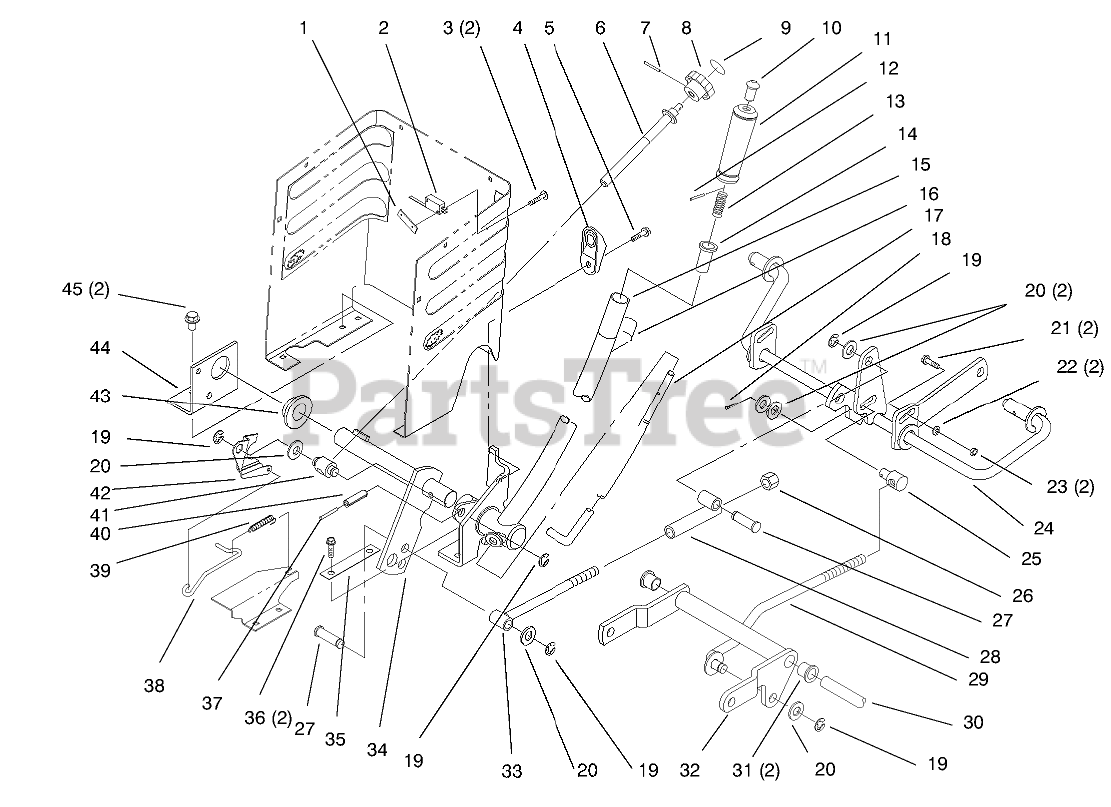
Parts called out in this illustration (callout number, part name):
1	NUT-SPEED
2	SWITCH-MICRO
3	SCREW-PPHTF
4	WEDGE - HOC
5	SCREW-HWH
6	ROD - HOC
7	PIN-SPIROL
9	DECAL-HEIGHT KNOB
10	TIP-ROD
11	GRIP-HANDLE
12	PIN-SPIROL
13	SPRING-COMPRESSION
14	RETAINER-SPRING
15	LEVER-LIFT
16	Decal-Lift (Only On: 72085)
16	Decal-Lift (Only On: 72104)
17	ROD-LEVER, LIFT
18	PIN-COTTER
19	RING-RETAINING, EXTERNAL
20	WASHER-FLAT
21	BOLT-CARR
22	WASHER-FLAT
23	NUT-LOCK, NI
24	SHAFT-GAGE
25	ROD-TRUNNION LIFT
26	NUT-LOCK, NI
30	SHAFT-PIVOT, PEDAL
31	BUSHING-FLANGE
32	ARM-PIVOT
34	SHAFT-LIFT
36	SCREW-HWHTF
37	PIN-SPRING
38	ROD - HOC INDICATOR
39	SPRING - EXTENSION
40	PIN-ROLL
41	TRUNNION
42	PLATE - HOC GAGE
43	BEARING-FLANGE
44	BRACKET-PIVOT, LINKAGE
45	SCREW-HWHTF
